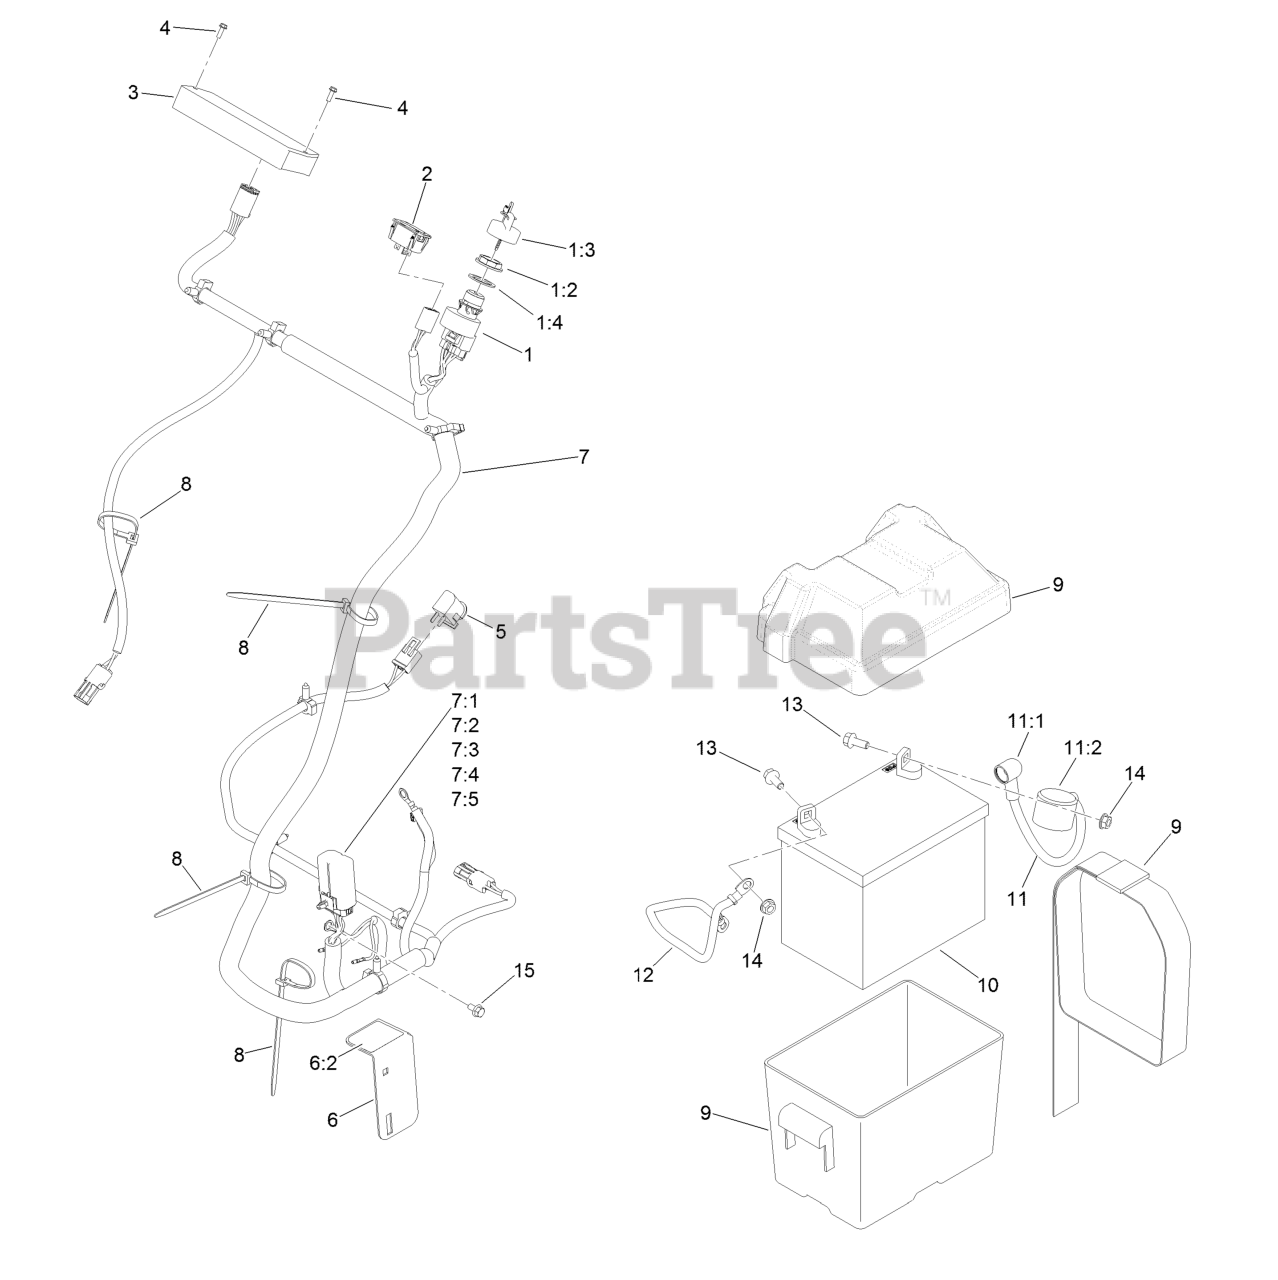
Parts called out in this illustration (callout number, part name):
1	Ignition Switch ASM
1:2	Nut-Mounting
1:3	Ignition Key Set
1:4	Washer-Backup
2	Hour Meter
3	Controller-Dc
4	Screw-HWHTF
6	Fuse Bracket ASM
6:2	Decal-Fuse
7	Harness-Wire
7:1	Fuse-Mini Blade, 20 Amp
7:2	Relay-Micro
7:3	Cap-Power Distribution Module
7:4	Clip-Power Distribution Module
7:5	Block-Foam
8	Tie-Cable 7 15/16 (Large)
9	Battery Box
10	Battery (300 CCA, Wet)
11	Cable-Battery, Positive
11:1	Insulator-Solenoid
11:2	Insulator-Battery
12	Cable-Battery, Negative
13	Screw-HHF 5/16-18 X 3/4 SS
14	Nut-Hex Flg
15	Screw-HHF
